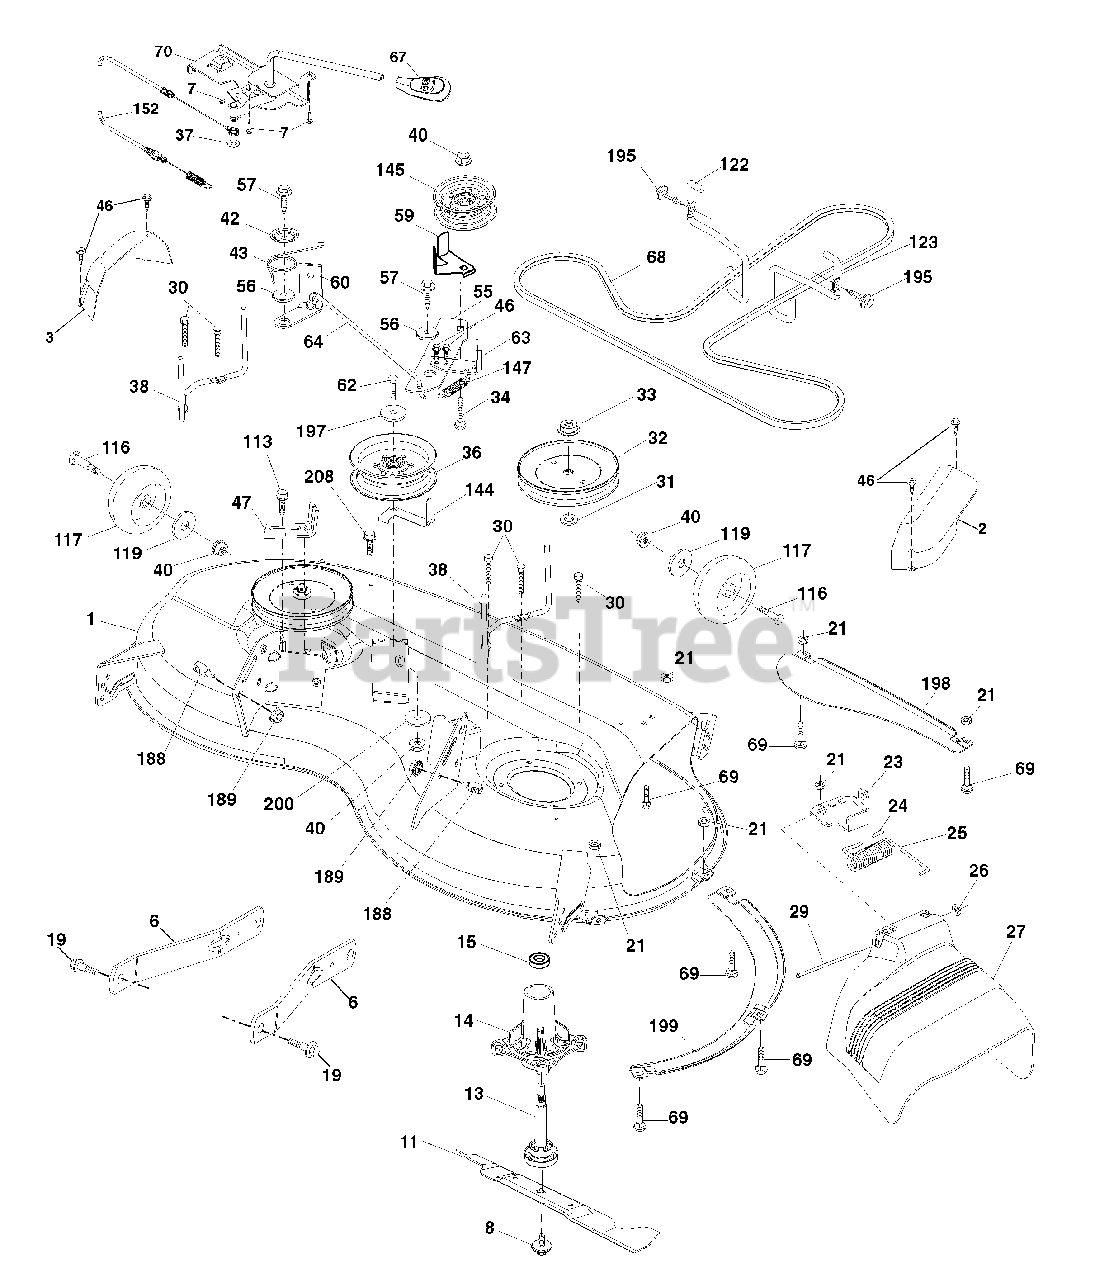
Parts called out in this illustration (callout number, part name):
1	Mower Housing
2	Cover Mandrel RH
3	Cover Mandrel LH
6	Arm Suspension
7	Screw # 10 x 0.750
8	Bolt/Washer asm 7/16-20 unf
11	Blade Mower Hi Lift
13	Shaft Assembly, Mandrel
14	Housing, Mandrel
15	Bearing, Ball, Mandrel
19	Bolt, Shoulder
21	Nut
23	Bracket, Deflector
24	Cap, Sleeve
25	Spring, Torsion, Deflector
27	Shield, Deflector
29	Rod, Hinge
30	Screw Thdrol Rolling Wsh Hd
31	Washer, Spacer
32	Pulley, Mandrel
33	Nut, Toplock, Flanged
34	Bolt Carr Sh. 3/8-16 x 1-1/2 Gr. 5
36	Pulley, Idler, Flat
37	Washer 13/32 x 13/16 x 16 Ga.
38	Keeper Belt LH Mandrel
40	Nut, Lock Flg. 3/8-16 unc
42	Spring Trosion Brake
43	Spring Torsion Retainer
47	Bracket Clutch Cable
55	Arm, Idler
56	Spacer, Retainer
57	Screw Hexwsh Thd 3/8-16 x 1
59	Guard, Tuv Idler
60	Arm Brake Mower LH
62	Bolt 3/8-16 UNC x 2-1/4 Gr. 5
63	Arm Brake Mower
64	Linkage Brake
67	Handle, Clutch Cable
68	V-Belt
69	Bolt
70	Clutch Asm. Cable
113	Screw 5/16-18
116	Bolt, Shoulder
117	Wheel, Gauge
119	Washer 13/32 x 1-1/4 x 12 Ga.
122	Keeper Belt Eng. LH
123	Keeper Belt Eng. RH
144	Keeper Belt
145	Pulley Idler
147	Spring Return
152	Cable Clutch Manual w/Spr.
188	Stud Fastener
189	Nut Lock Hex Flange
195	Screw 3/8-16 x 3/4
197	Washer 13/32 x 13/16 x 12 Ga.
198	Baffle Center Front
199	Baffle Front RH
200	Washer 13/32 x 1 x 1/2 11 Ga.
208	Screw 3/8-16 x 1/2
208	Mandrel Assembly
208	Replacement Mower, Complete
